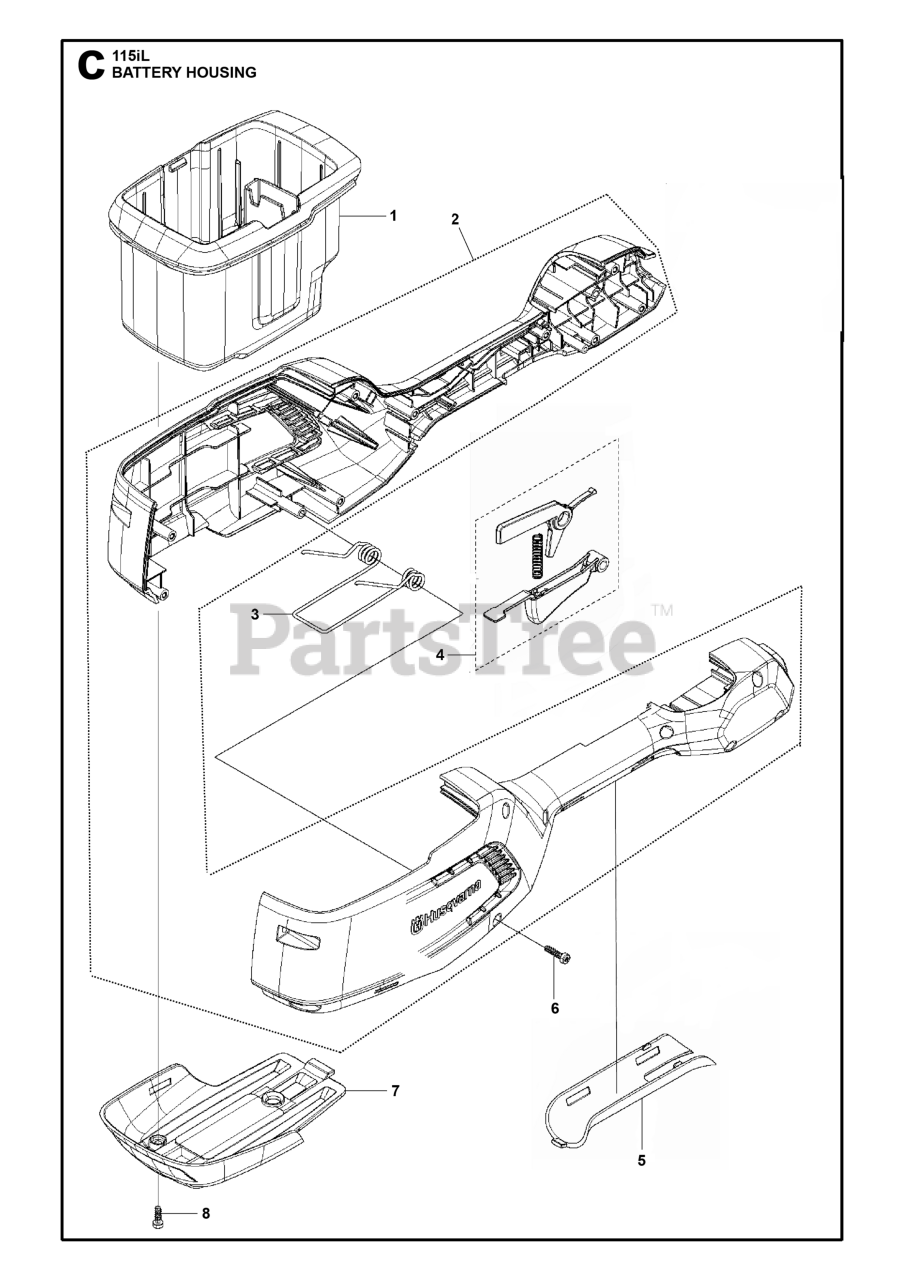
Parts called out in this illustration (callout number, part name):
1	COVER BATTERY GREY
2	HOUSING ASSY
3	SPRING POP UP
4	TRIGGER ,TRIGGER ASSY
5	COVER REAR HANDLE GREY
6	SCREW ST4X16
7	PLATE BACK GREY
8	SCREW ST4X12
